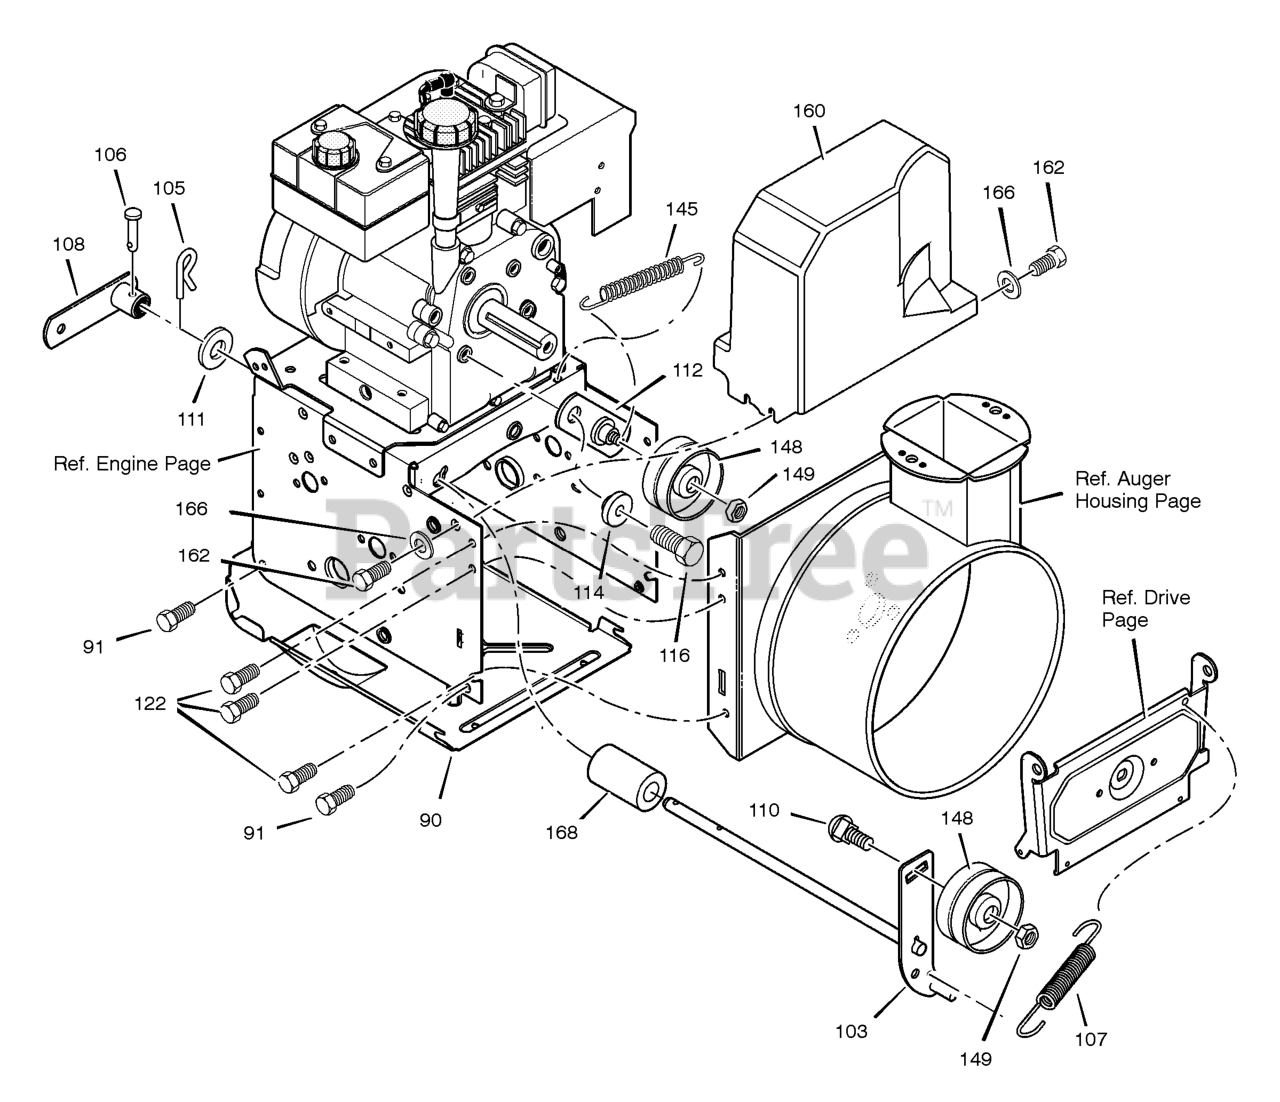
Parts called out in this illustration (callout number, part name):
88	SCREW, 5/16-18 x 0.50
90	COVER, BOTTOM
91	SCREW, 1/4-20X .63
103	IDLER ASSEMBLY, AUGER
105	PIN, HAIR .38DIAX1.64LG
106	PIN, CLEVIS 3/16" DIA
107	SPRING, TENSION
108	ASSY., SPRING ATTACH
110	BOLT, 3/8-16X1.25 CARR.
111	WASHER, FLAT
112	BRACKET ASSEMBLY, IDLER
114	BUSHING, IDLER BRACKET
116	SCREW 5/16-24 X .75
118	WASHER, SPLIT
122	SCREW, TAP 5/16-18 X .50
145	SPRING, IDLER TRACTION DRIVE
148	PULLEY, IDLER
149	NUT, JAM 3/8-16
160	COVER, BELT
162	SCREW, TAP 1/4-20 X .75
166	WASHER, FLAT
168	SPACER, AUGER BRACKET
